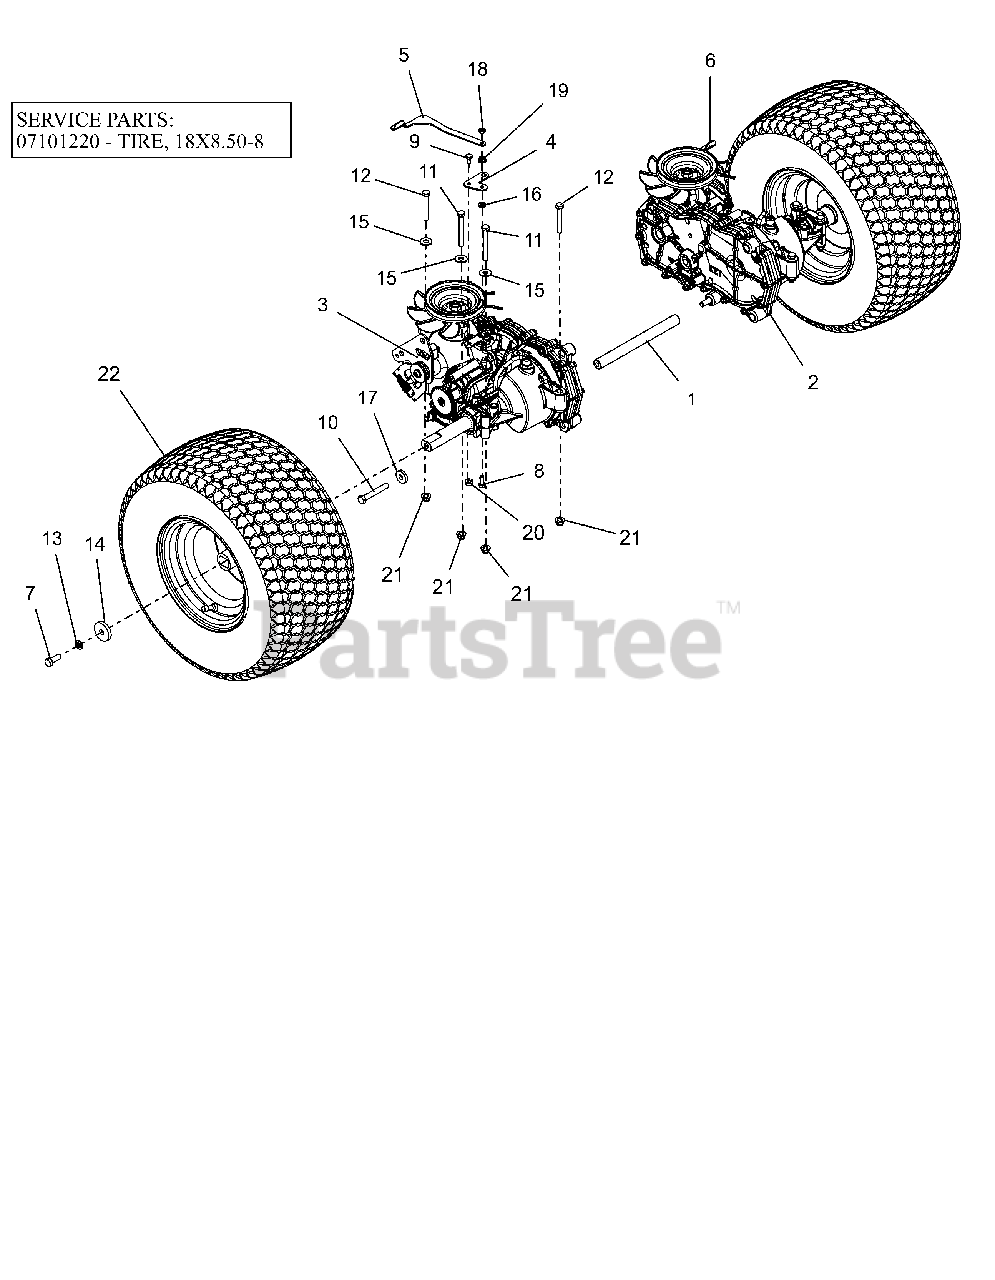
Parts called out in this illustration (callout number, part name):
1	ROD, TRANSAXLE BRACE
2	TRANSAXLE,LH EZT D-SHFT SHORT
3	TRANSAXLE,RH EZT D-SHFT SHORT
4	BRKT, DUMP VALVE EXTENSION
5	BRKT, DUMP VALVE RH
6	BRKT, DUMP VALVE LH
7	BLT-HEX .38-16X1.0 GR8 YZ EP30
8	@BLT-HEX .25-20X.75 GR5 YWZC
9	@BLT-HEX .25-20X.50 GR5 YWZC
10	@BLT-HEX .38-16X2.50 GR5 YWZC
11	@BLT-HEX .31-18X2.75 GR5 YWZC
12	@BLT-HEX .31-18X2.25 GR5 YWZC
13	@WSHR-LK .38X.094 REG YWZC
14	WSHR,FLT STL.406X1.50X.245YWZC
15	@WSHR-FL-STL.38X.875X.083 YWZC
16	WSHR-FL-STL .265X.50X.087YWZC
17	WSHR-FL-STL .406X1.00X.188 YWZ
18	NUT-LK-CTR JAM .25-20 YWZC
19	@NUT-SPNLK-FLG .25-20 YWZC
20	@NUT-LK-TOP-FLG .25-20 YWZC
21	@NUT-LK-NYL-FLG .31-18 YWZC
22	ASM, WHL/TIRE 18X8.50-8 DHUB
22	TIRE, 18X8.50-8
